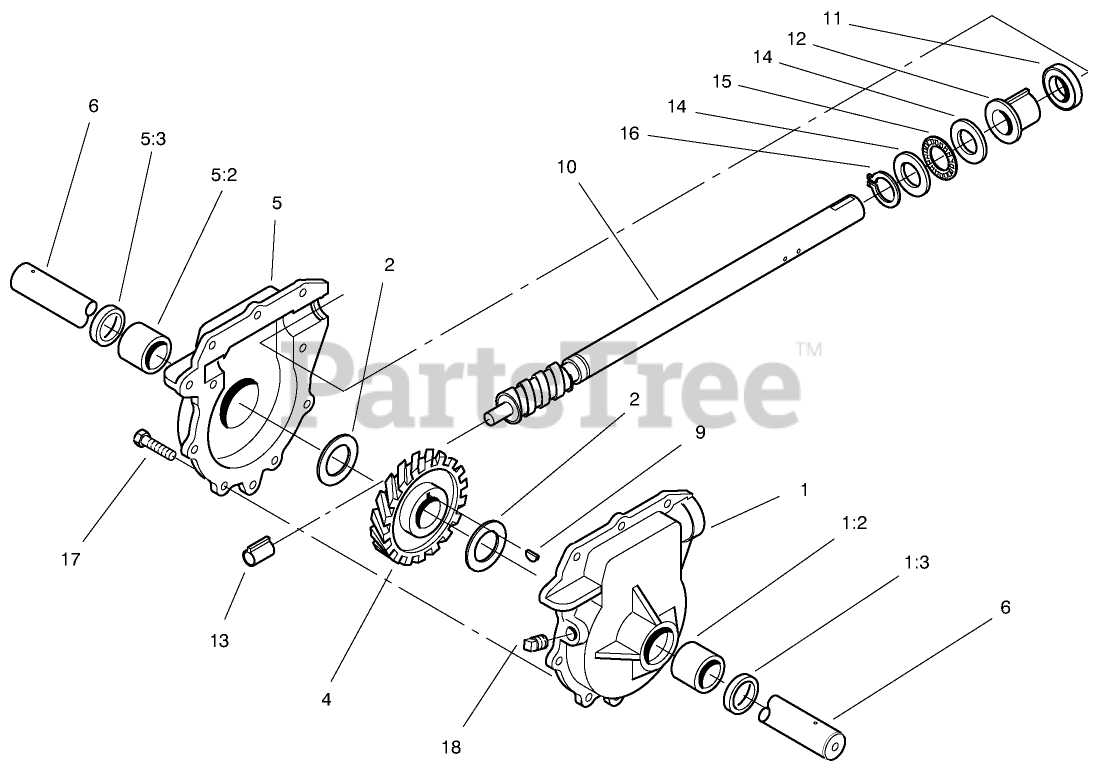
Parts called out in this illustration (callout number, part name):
1:2	BUSHING
1:3	SEAL-OIL
2	WASHER-THRUST
4	GEAR-HELICAL
5:2	BUSHING
5:3	SEAL-OIL
6	SHAFT-AUGER
9	KEY-WOODRUFF
10	SHAFT-IMPELLER
11	SEAL-OIL
12	BUSHING-INPUT
13	BUSHING-WORM
14	WASHER-THRUST
15	BEARING-THRUST
16	RING-RETAINING, EXT
17	SCREW-HWH
18	PLUG-PIPE, SQH
